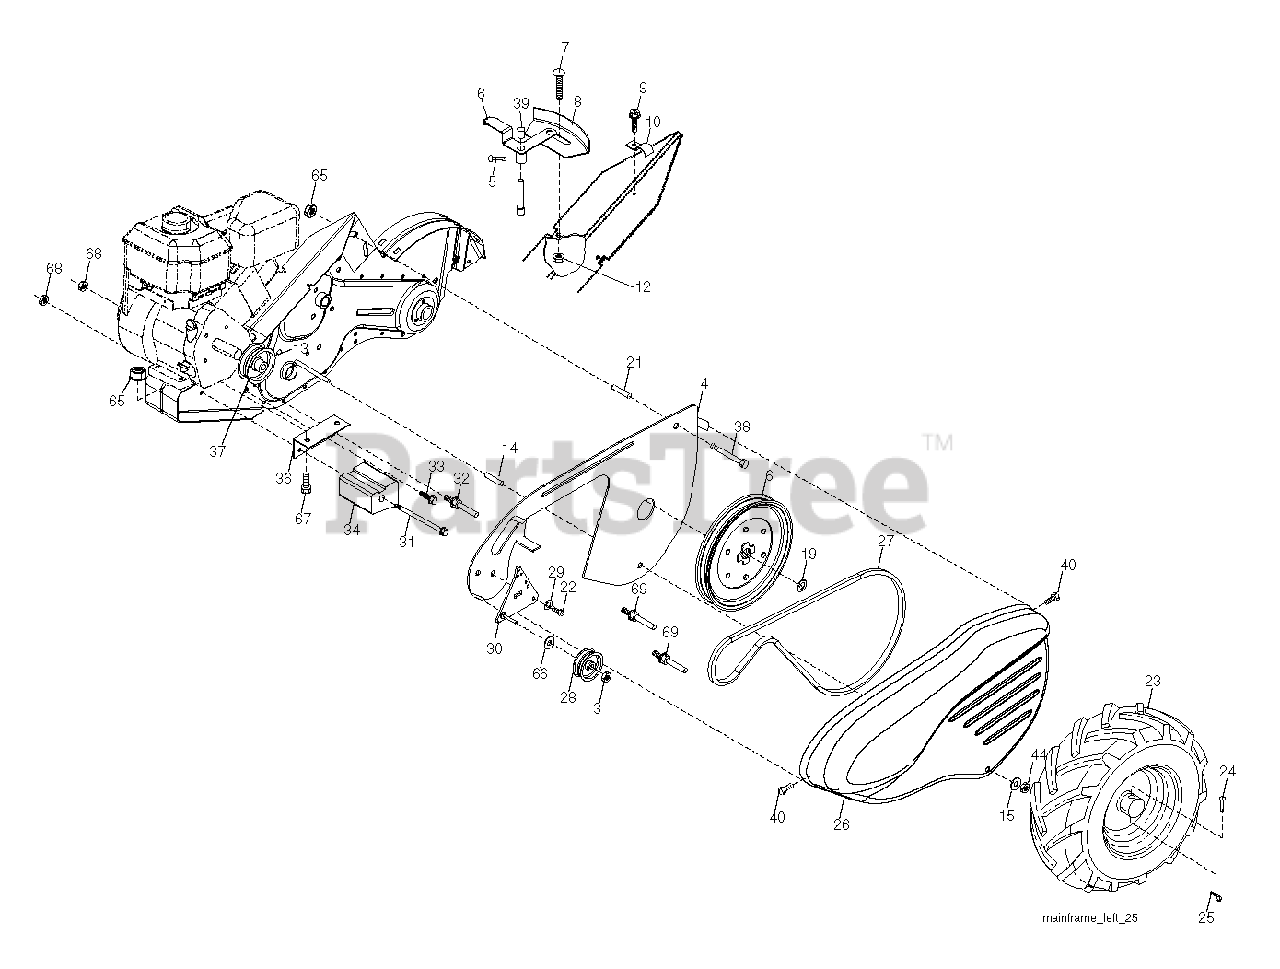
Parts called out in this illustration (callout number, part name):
3	NUT.HEX.3/8-16UNC
4	SHIELD.INNER.BELT.GUARD.RT
5	PIN.SPIROL.FLARED
6	LEVER ASM CRT
8	PANEL.INDICATOR.SHIFT.BLACK
10	CONDUIT CLIP T
12	NUT
13	SET SCREW
14	SPACER-SPLIT.327 X .42
15	WASHER
16	SHEAVE, TRANSMISSION
19	RETAINING RING LT
21	SPACER CRT
23	TIRE.CHV.13X5-6
24	RIVET,DRILLED
26	GUARD.BELT.TILLER.YELLOW
27	V-BELT
28	PULLEY-IDLER TI
29	KLIP RING
30	BRACKET.ASM.IDLER.BLACK
31	BOLT CRT
32	SHIFT ARM CRT
33	BOLT
34	COUNTERWEIGHT, RH
36	BRACKET LH CRT
37	ENGINE PULLEY
39	CAP.PLUNGER.BLACK
40	SCREW.HEX.WSH.SLT.#10-24X.50
44	NUT.71038.31-18.HEX.NYLOCK
65	LOCKNUT-FLANGE 5/16-18
66	WASHER
67	BOLT
69	KEEPER.BELT.ENGINE
